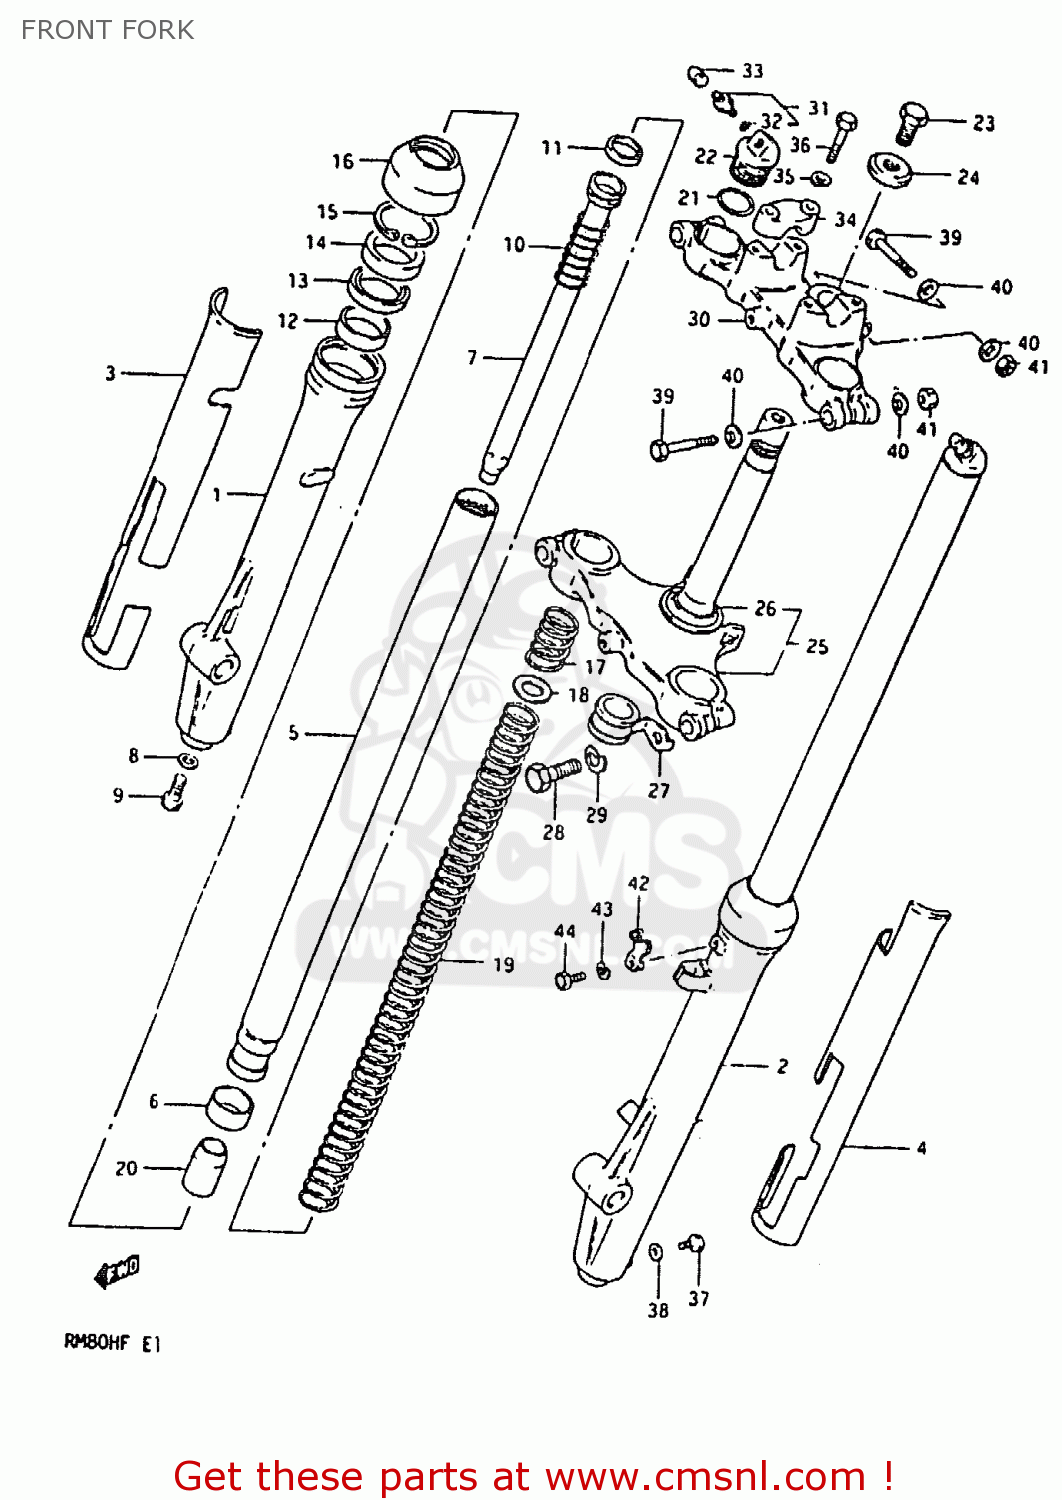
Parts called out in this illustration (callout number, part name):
1	TUBE, OUTER RH
2	TUBE, OUTER LH
3	PROTECTOR, RH
4	PROTECTOR, LH
5	TUBE, INNER
6	PISTON
7	PIPE, SEAT
8	GASKET (NAS)
9	BOLT(8X27)
10	SPRING,FORK REBOUND
11	RING,PISTON
12	BUSH,GUIDE
13	SPACER,SEAL
14	OIL SEAL,FRONT FORK
15	CIRCLIP,FORK OIL SEAL
16	DUST SEAL,FR FORK
17	SPRING A
18	SPRING,JOINT
19	SPRING B
20	PIECE, OIL LOCK
21	O RING
22	BOLT
23	BOLT
24	WASHER
25	STEM, STEERING (PEARL METALLIC)
26	RACE,STEERING OUTER LWR
27	CLIP
28	BOLT
29	WASHER,LOCK 12
30	STEM HEAD, STEERING
31	VALVE,AIR
32	O-RING (D:3.8 ID:19)
33	CAP,VALVE AIR
34	HOLDER,HANDLEBAR
35	LOCK WASHER
36	BOLT
37	BOLT(6X8)
38	GASKET,DRAIN,PLUG (NAS)
39	BOLT
40	WASHER
41	NUT
42	HOLDER
43	LOCK WASHER
44	BOLT
